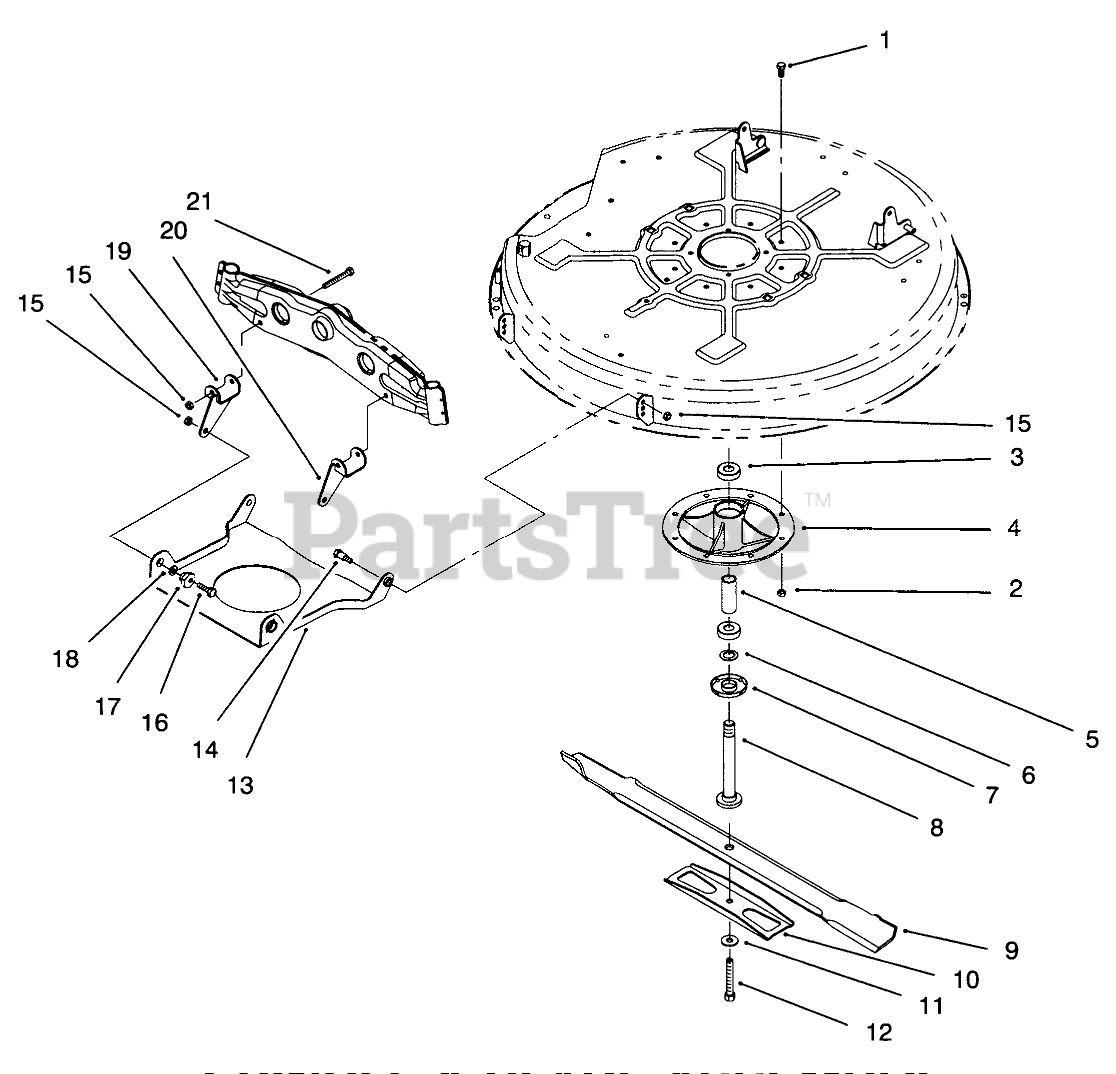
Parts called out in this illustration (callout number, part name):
1	SCREW-HH
2	NUT-LOCK, NI
3	BEARING-BALL
4	SPINDLE
5	SPACER-BEARING
6	SPACER-HARDNED
7	SHIELD-BEARING
8	SHAFT-SPINDLE
9	Blade
9	BLADE-RECYCLER
10	STIFFENER
11	WASHER-BELLEVILLE
12	SCREW-HH
13	Pan-Front Deck Susp.
14	BOLT-SHOULDER
15	NUT-LOCK, NI
16	SCREW-HH
18	WASHER-PLAIN
19	Bracket-R.H.
20	Bracket-L.H.
21	SCREW-HH
